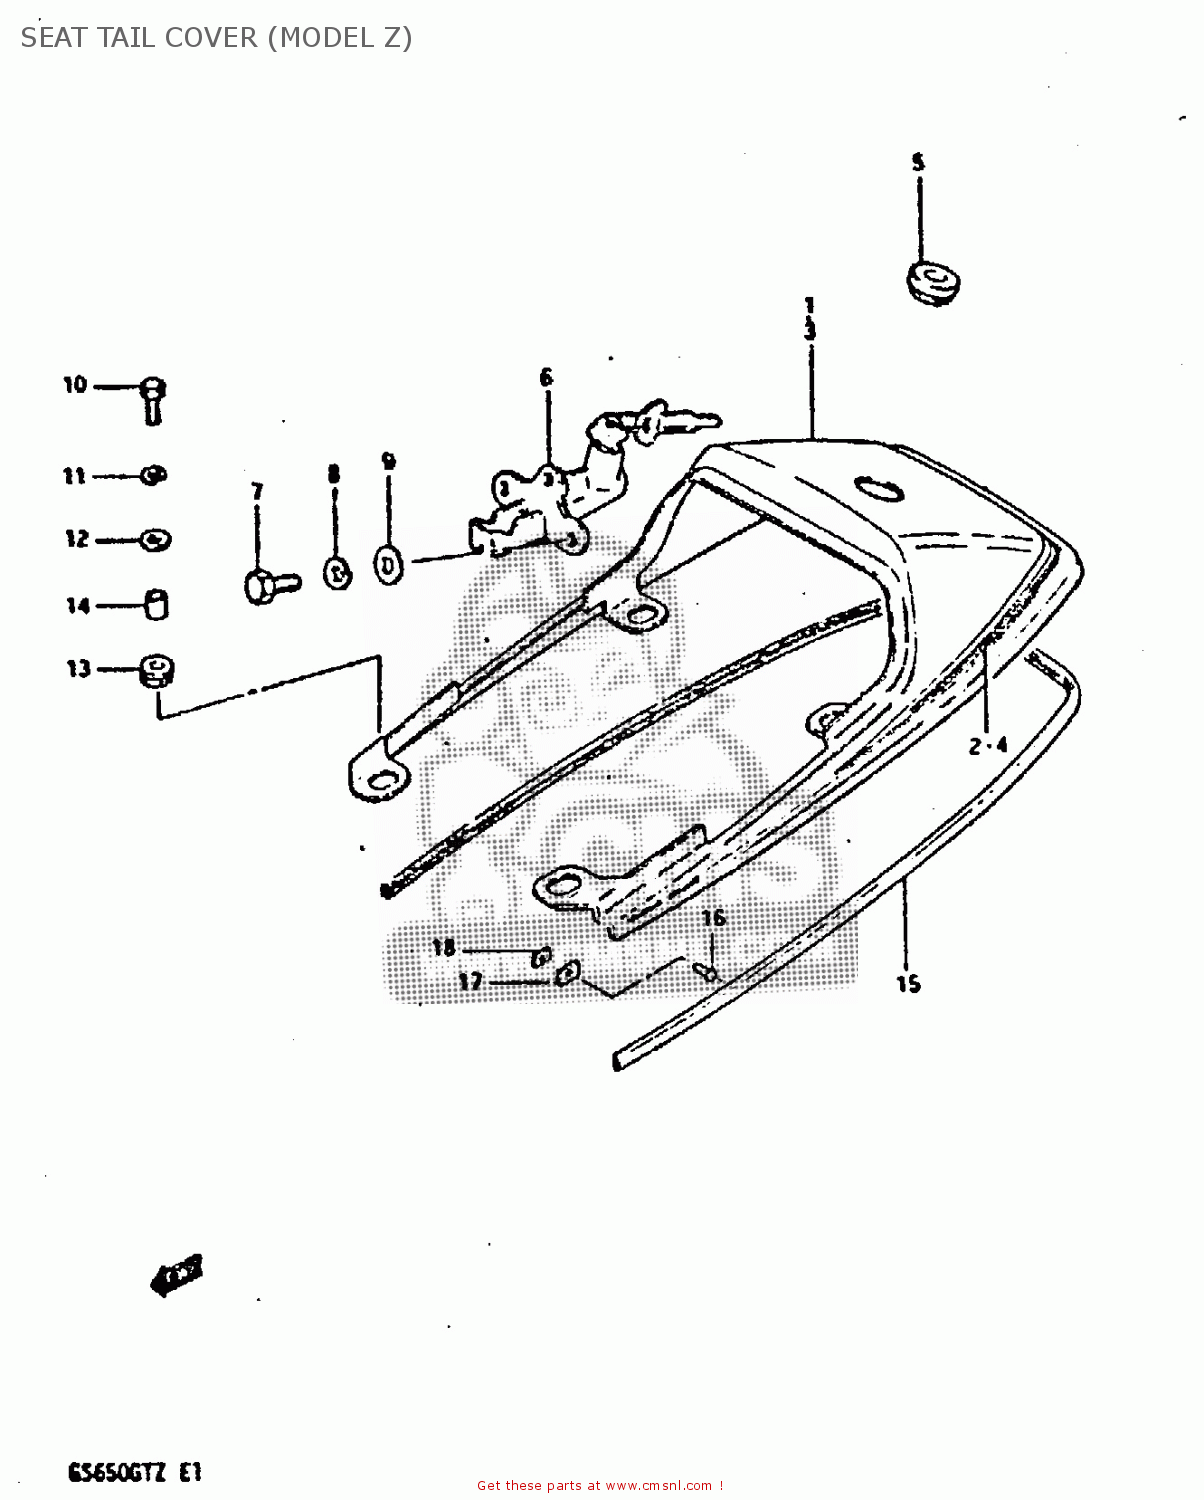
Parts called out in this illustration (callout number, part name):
1	BOX ASSEMBLY,SEAT TAIL
2	TAPE SET,BOX SEAT TAIL
3	COVER, SEAT TAIL (MAROON)
4	TAPE SET,BOX SEAT TAIL
5	GROMMET,SEAT LOCK HOLE
6	LOCK SET,SEAT
7	BOLT
8	LOCK WASHER
9	WASHER
10	BOLT
11	LOCK WASHER
12	WASHER(6,5X22X1.6)
13	CUSHION
14	SPACER(6.5X10.5X12)
15	MOLDING,SEAT TAIL COVER
16	RIVET
17	CUSHION,SEAT TAIL
18	NUT
